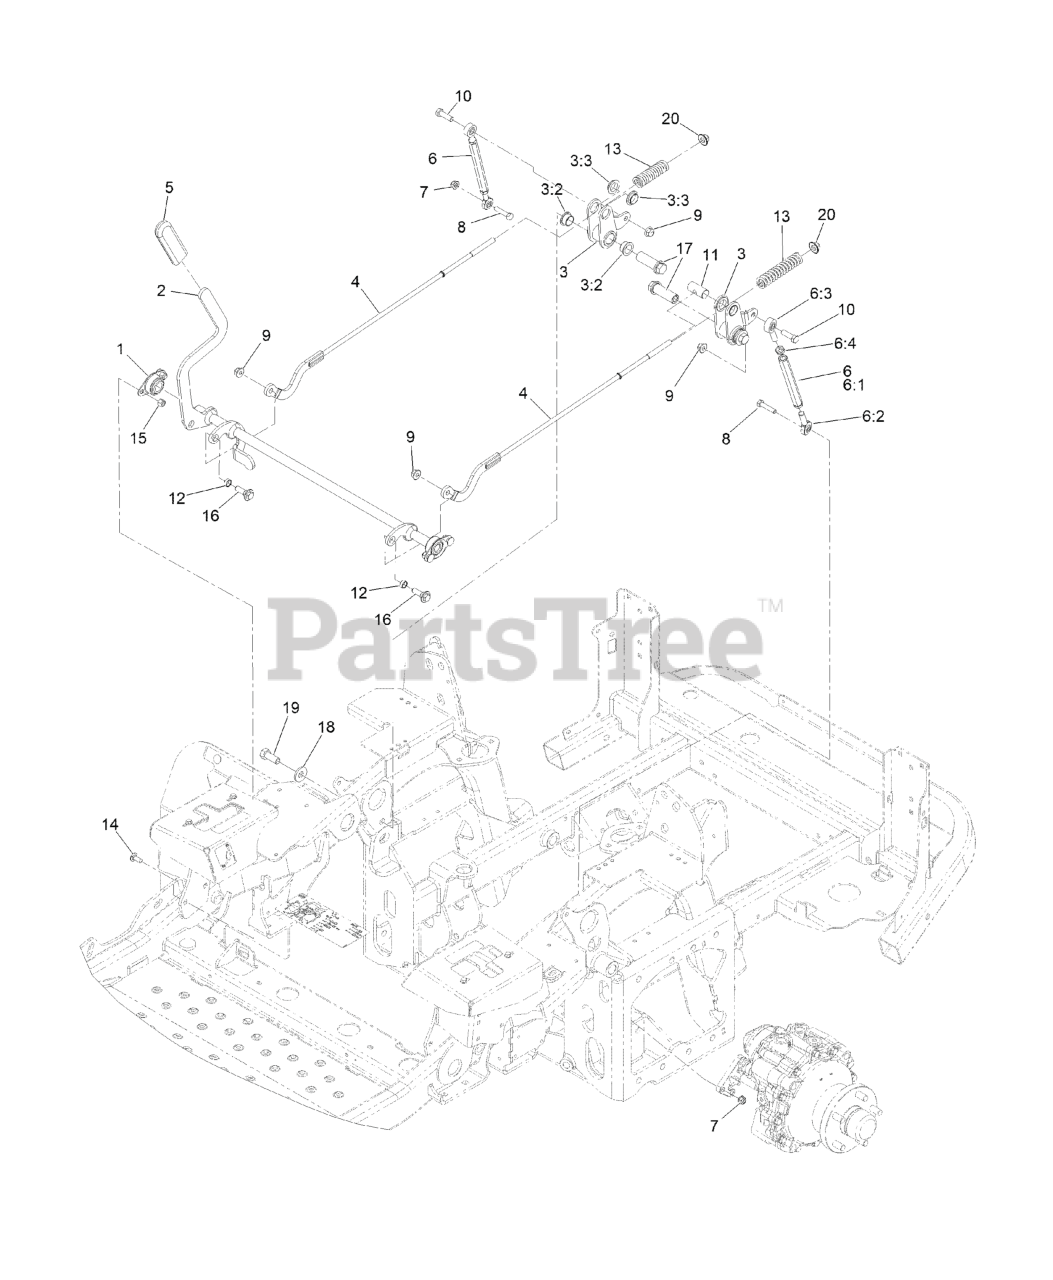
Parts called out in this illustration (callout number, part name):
1	BEARING-FLANGE, SIDE
2	SHAFT-BRAKE
3	BRAKE BELLCRANK ASM
3:2	BUSHING-FLANGE
3:3	BUSHING-FLANGE
4	LINK-BRAKE, UPPER
5	GRIP-LEVER
6	TURNBUCKLE ASM
6:1	TURNBUCKLE
6:2	BEARING-END, LH ROD
6:3	BALLJOINT
6:4	NUT-HJ
7	NUT-HF, NI
8	SCREW-HH
9	NUT-HF, NI
10	SCREW-HH
11	PIN-TRUNION
12	BEARING-SLEEVE
13	SPRING-COMPRESSION
14	SCREW-CARR
15	NUT-LOCK, NI
16	SCREW-SHOULDER, HWH
17	HUB-THREADED
18	WASHER-SPRING
19	SCREW-HH
20	Nut-Nyloc 3/8-16 Flg
